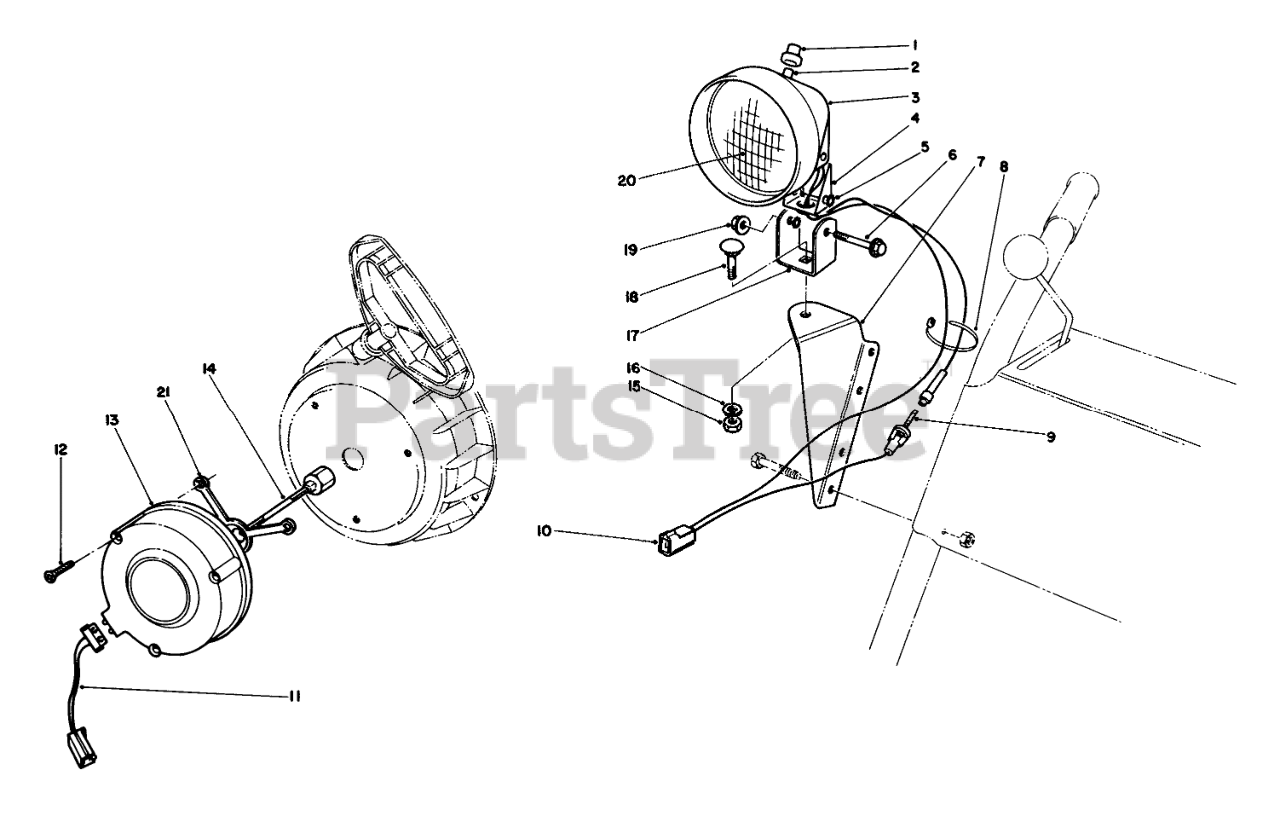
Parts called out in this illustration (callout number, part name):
1	BOOT-SWITCH
2	SWITCH ASM
3	Bucket-Headlamp
4	TO BE DISCONTINED-NOT NEEDED ON PRODUCT
5	WASHER-LOCK
6	SCREW-HH
7	LAMP MOUNT B
8	TIE-CABLE
9	Fuse-7-1/2 Amp.
10	WIRE ASM
11	Connector-Wire
12	SELF TAPPING SCREW
13	Alternator
14	Shaft-Alternator, 3 Inch
15	NUT-HEX
16	WASHER-LOCK
17	BRACKET
18	BOLT-CARR
19	NUT-HF
20	BEAM-SEALED
21	SPACER
